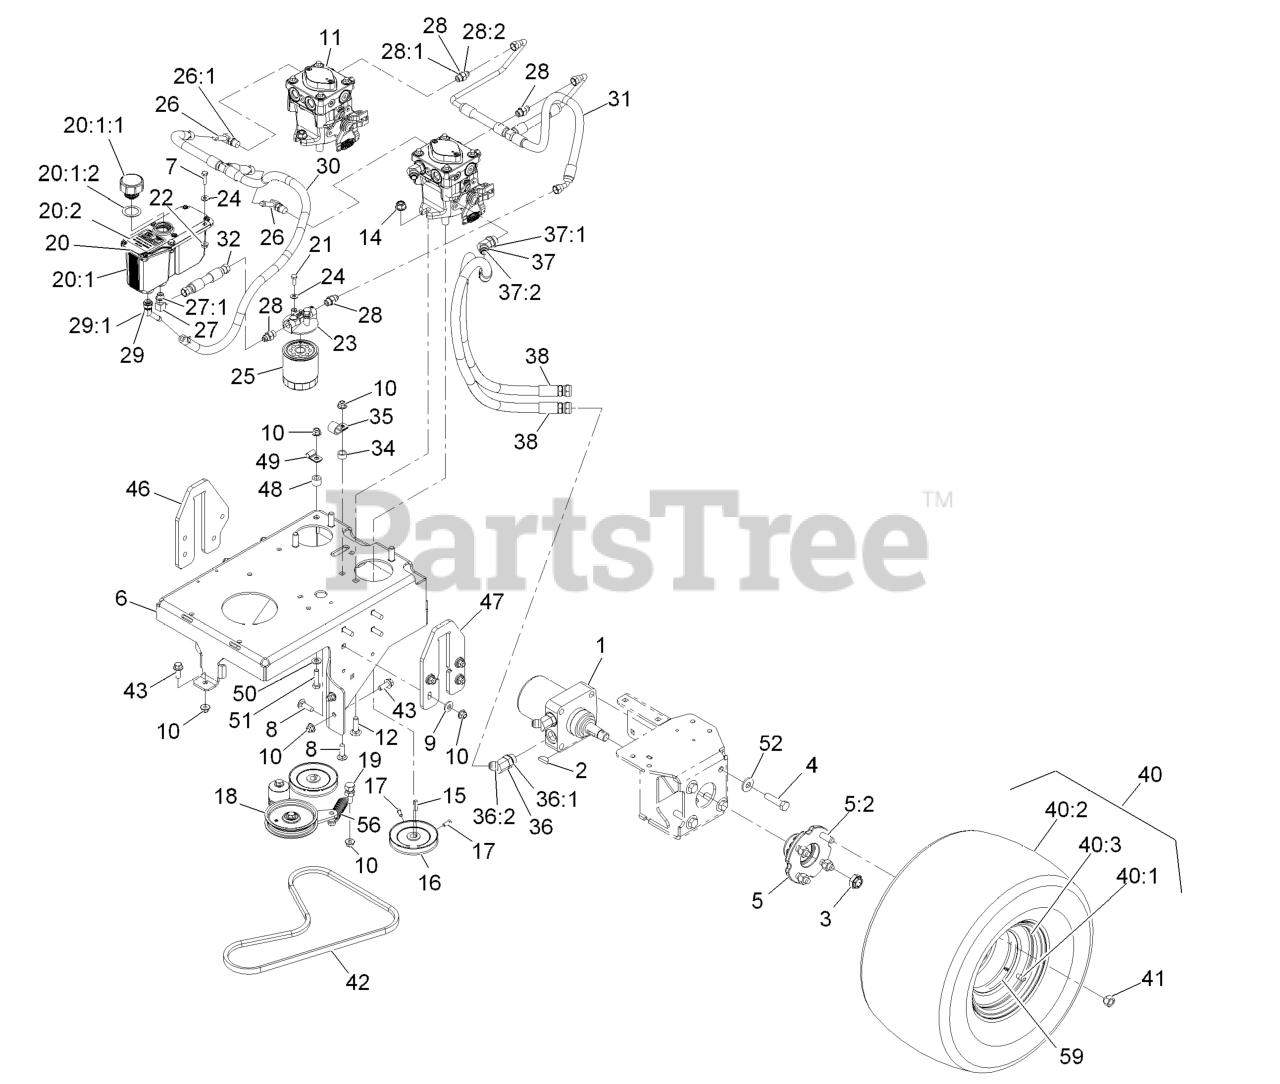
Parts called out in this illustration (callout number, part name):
1	MOTOR-WHEEL
2	KEY-WOODRUFF
3	NUT-LOCK
4	SCREW-HH
5	WHEEL HUB ASM
5:2	STUD-TYPE, DRIVE
7	SCREW-HH
8	BOLT-CARR
9	WASHER-BELLEVILLE
10	NUT-HF, NI
11	PUMP - HYDRAULIC
12	SCREW-HH
14	NUT-HF, NI
16	PULLEY-PUMP
17	SCREW-SET
18	PUMP IDLER ASM
20	RESERVOIR ASM
20:1	Reservoir-Hyd
20:1:1	Cap-Reservoir, HYD
20:1:2	GASKET-CAP
20:2	DECAL-HYDRAULIC TANK
21	SCREW-HH
22	NUT-HHF
23	HEAD-FILTER
24	WASHER-FLAT
25	FILTER-25 MICRON, BI-DIRE
26	FITTING-ELBOW, 90
26:1	O-RING
27	FITTING-ELBOW, 90 DEG
28	FITTING-STRAIGHT
29	FITTING-BARBED, 45 DEG
29:1	O-RING
30	TANK HOSE ASM
31	HOSE ASSEMBLY - CHARGE
32	HYD HOSE ASM
34	SPACER-WHEEL
35	CLIP-LOOM
36	FITTING-HYD, 45 DEG
37	FITTING-HYD, 45 DEG
40	WHEEL ASM
40:1	Stem-Valve
40:3	RIM-8 INCH
41	NUT-LUG
42	BELT-V, LOWER PTO
43	SCREW-HHF 3/8-16 X 1
46	PLATE-LIFT, RH
47	PLATE, LIFT LH
48	SPACER-PIVOT
49	CLIP-TUBE
50	WASHER-FLAT
51	SCREW-HH
52	WASHER-SPRING
56	SPRING-EXTENSION
